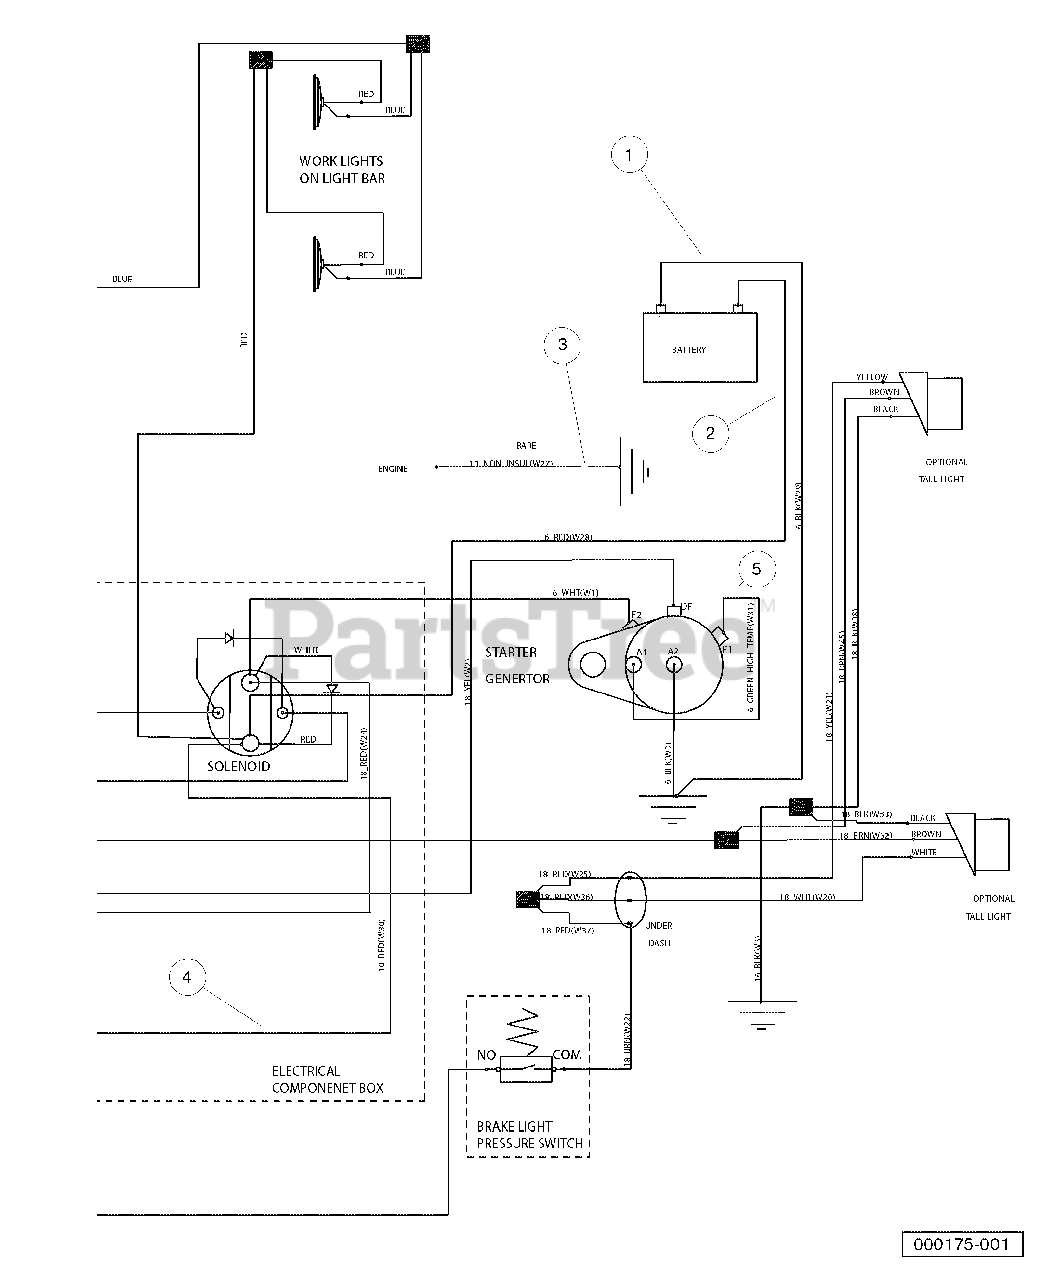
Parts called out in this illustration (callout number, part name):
1	Wire Assy, #6 Black
2	Wire Assembly #6 Red
3	Wire Assembly, #10, Uninsulated
4	Wire Assy, #10 Red
5	Wire Assy, #6 Green
6	Asm, Wire Harness
